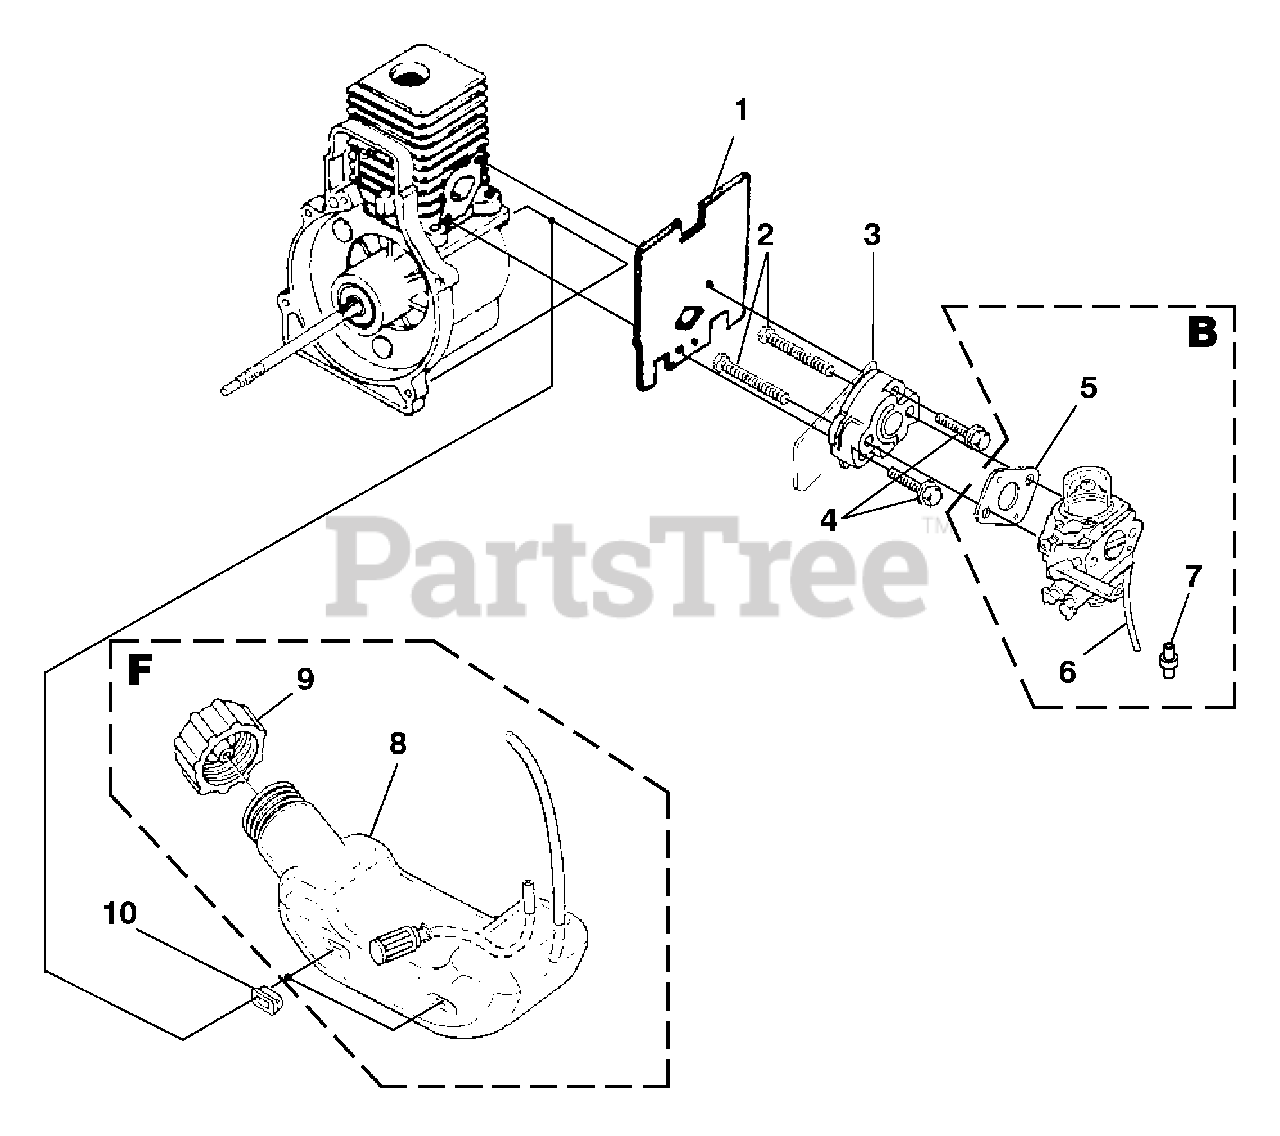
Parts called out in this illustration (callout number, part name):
1	GASKET-Heat Dam
2	SCREW- Machine (10-24 X 2 1/411)
3	HET DAM
4	SCRESems (10-24 X 1
5	GASKETCarburetor
7	FITTINIlie
8	FUEL TANK
9	FUEL CAP
10	BUMPERRubber
B	CRURETOR KIT
F	FUEL TNK ASSY.
